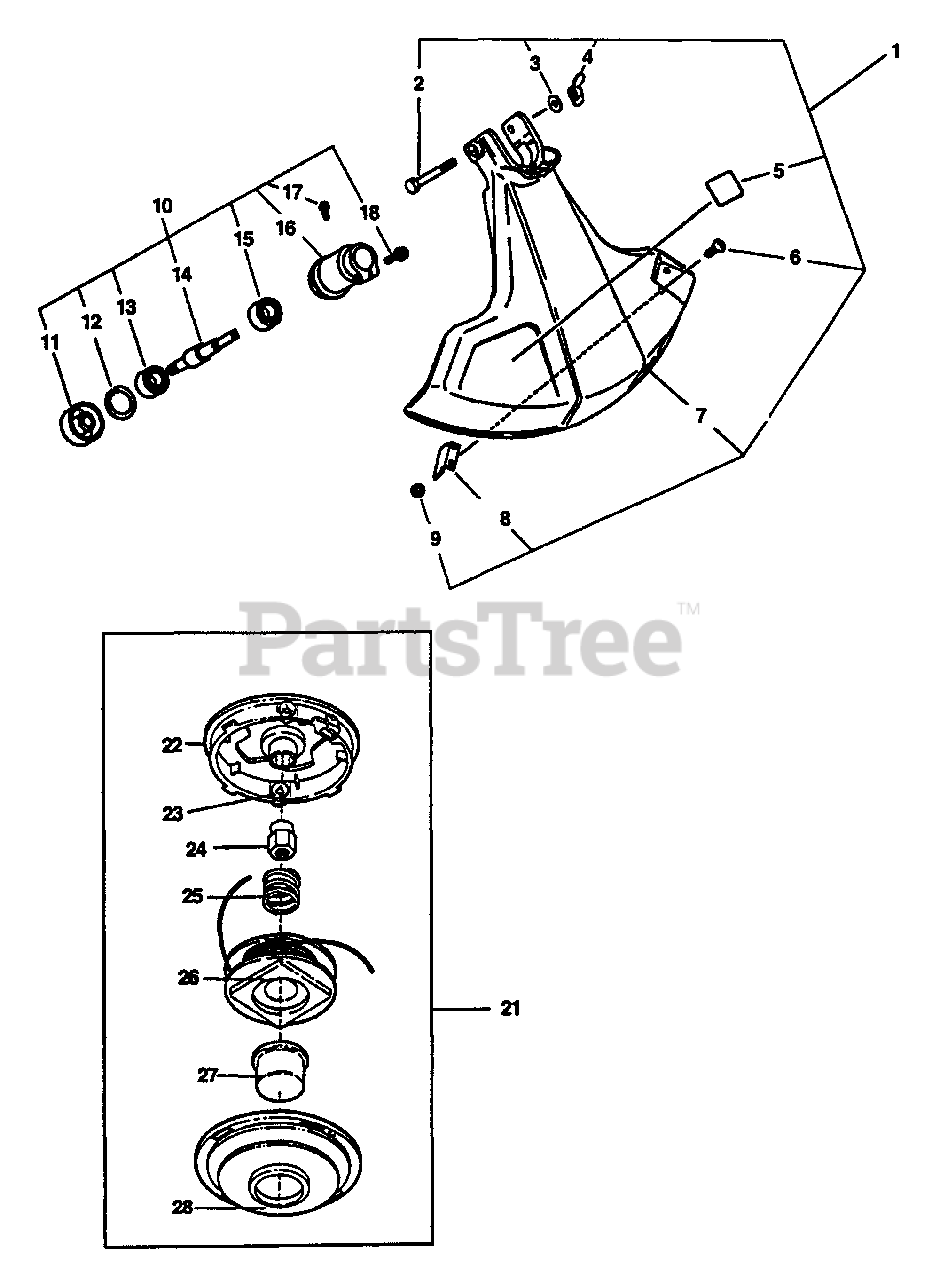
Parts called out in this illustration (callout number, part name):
1	DEBRIS SHIELD KIT
2	BOLT - 1/4-20 X 2"
3	WASHER - 1/4"
4	NUT - 1/4-20
5	LABEL - CAUTION
6	SCREW - 5X16
7	SHIELD, DEBRIS - PLASTIC
8	KNIFE, TRIMMER LINE
10	GEAR CASE ASSY
11	ADAPTOR, BLADE - UPPER
12	RING, RETAINING - 30
13	BEARING, BALL - 6200
14	GEAR - SHAFT
15	BEARING, BALL - 6200
16	CASE, GEAR
17	SCREW - 4X10
18	BOLT - 5X25
21	KNIFE, TRIMMER LINE
22	HOUSING
23	EYELET
24	BOLT
25	SPRING
26	SPOOL ASSY
27	BUTTON
28	COVER
